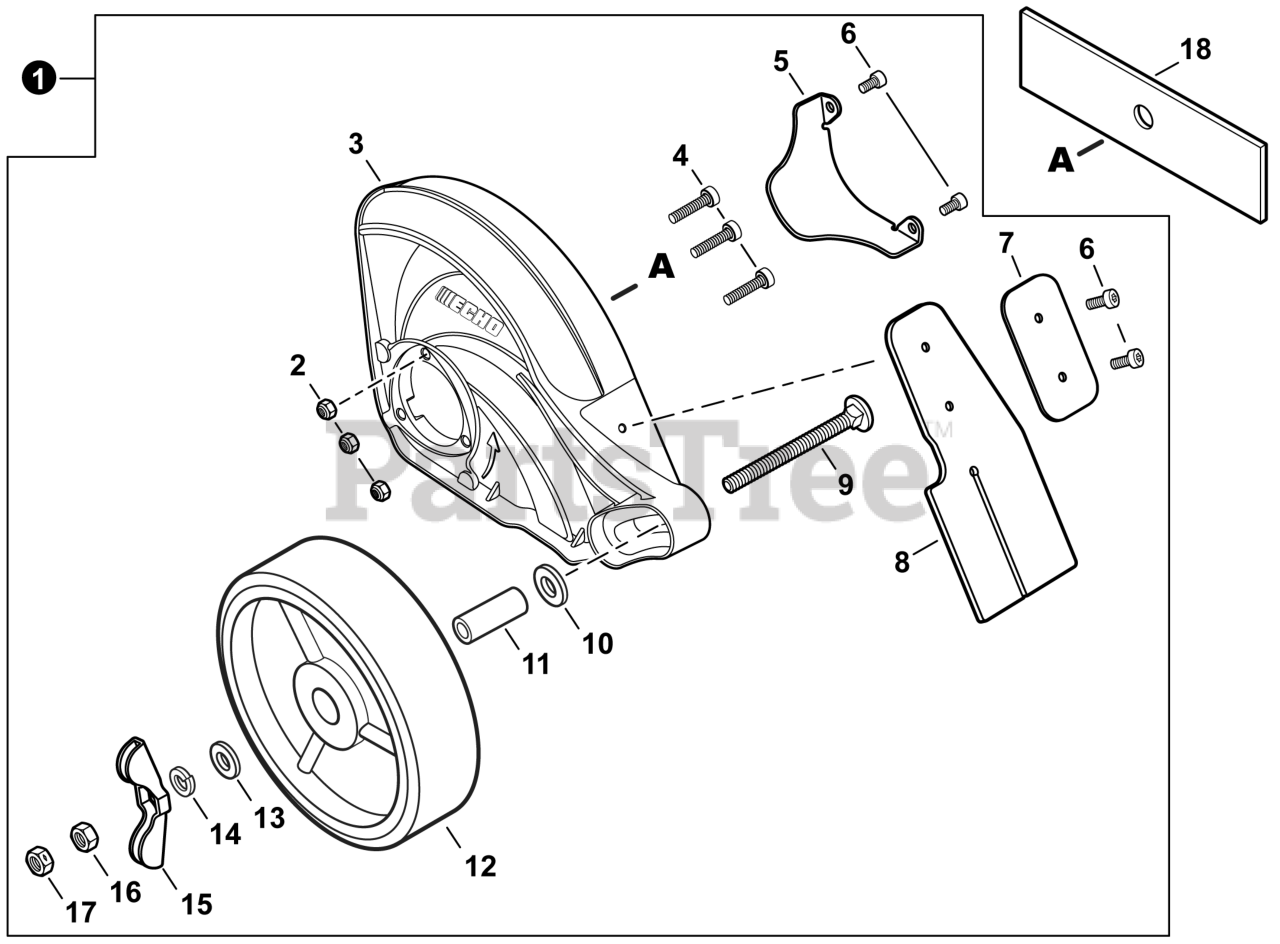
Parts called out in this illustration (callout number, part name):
1	SHIELD KIT, EDGER
2	NUT, LOCK M5
3	SHIELD, BLADE
4	BOLT, TORX 5x20
5	GUARD, SHIELD
6	BOLT, TORX 4x12
7	PLATE, FLAP
8	FLAP, DEBRIS
9	BOLT M8-1.25x80 MM
10	WASHER M10
11	COLLAR 12
13	WASHER 8
14	WASHER, SPRING 8
15	KNOB, FASTENER
17	NUT, LOCK M8
18	BLADE - 2 PK
